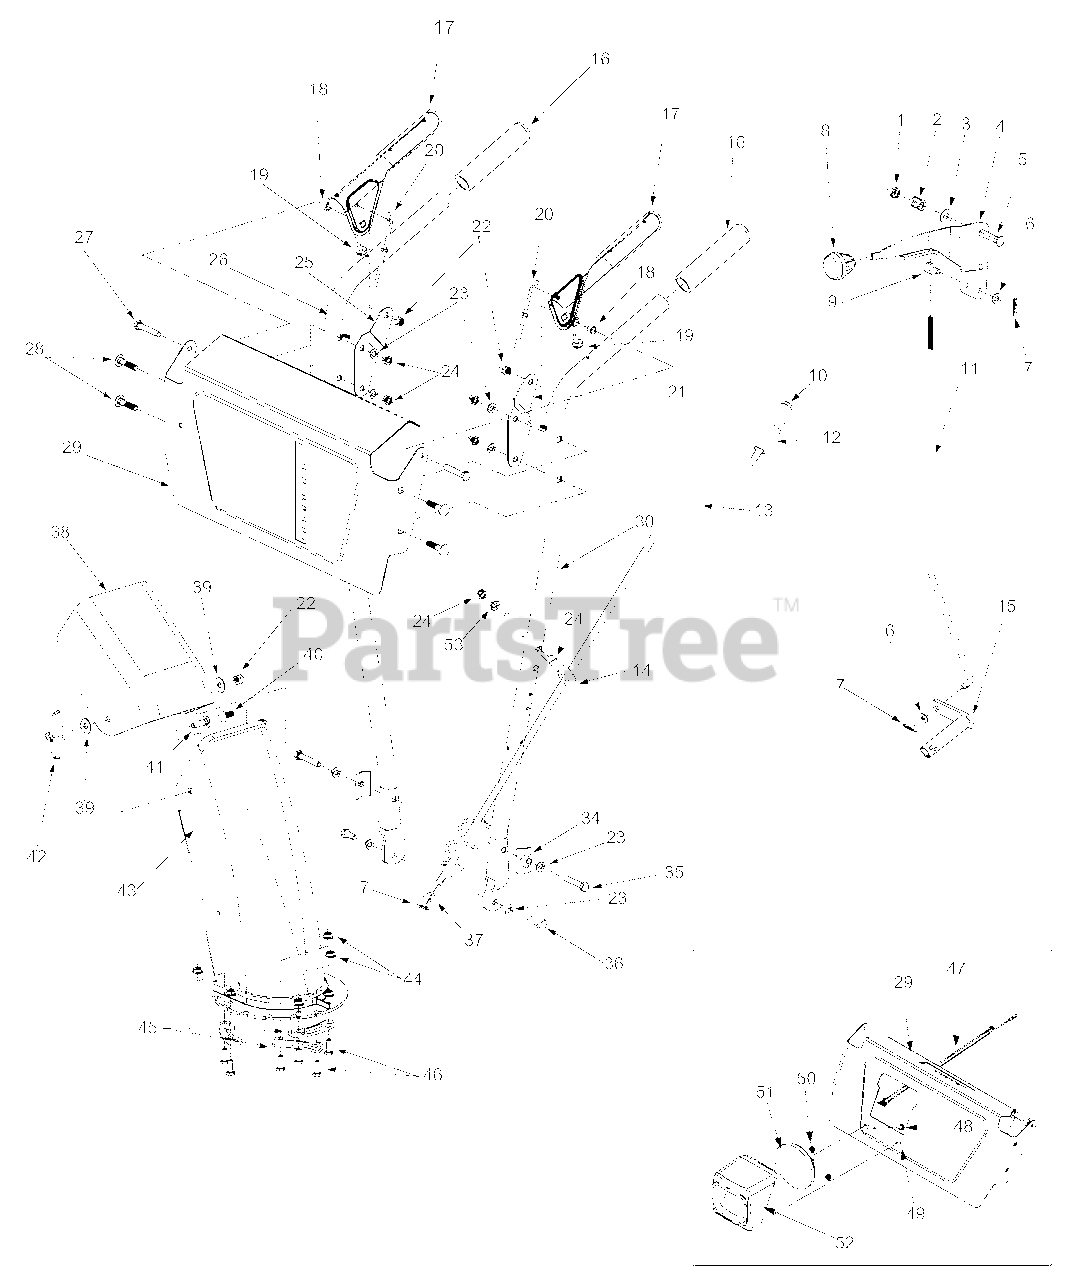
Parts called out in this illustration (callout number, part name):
1	Jam Lock Nut 3/8-24
2	Compression Spring
3	Bell Washer
6	Flat Washer
7	Cotter Pin
8	Shift Knob
9	Ferrule
10	Push Cap
11	Shift Rod
12	Chute Knob
13	Chute Directional Control
14	Eyebolt
17	Clutch Lever Assy LH
18	Spacer
19	Rubber Bumper
20	"Z" Fittings For Control Cables
23	Lock Washer 5/16
24	Hex Nut 5/16-18
28	Carriage Bolt 5/16-18 x 1.50
35	Hex Cap Screw 5/16-18 x 2.0
36	Hex Cap Screw 5/16-18 x .75
37	Flat Washer
38	Upper Chute
39	5/16 Washer
40	Carriage Bolt 5/16-18 x .75
41	Carriage Screw 5/16-18 x 1.0
43	Lower Chute
44	Hex Lock Nut 1/4-20
45	Flange Keeper
46	Hex Cap Screw 1/4-20 x .75
47	Round Light Harness
48	Hex Tap Screw 1/4-20 x .625
49	Hex Screw
50	Hex Nut
51	Headlight 18 Watts
52	Headlight Cover
53	Bell Washer
